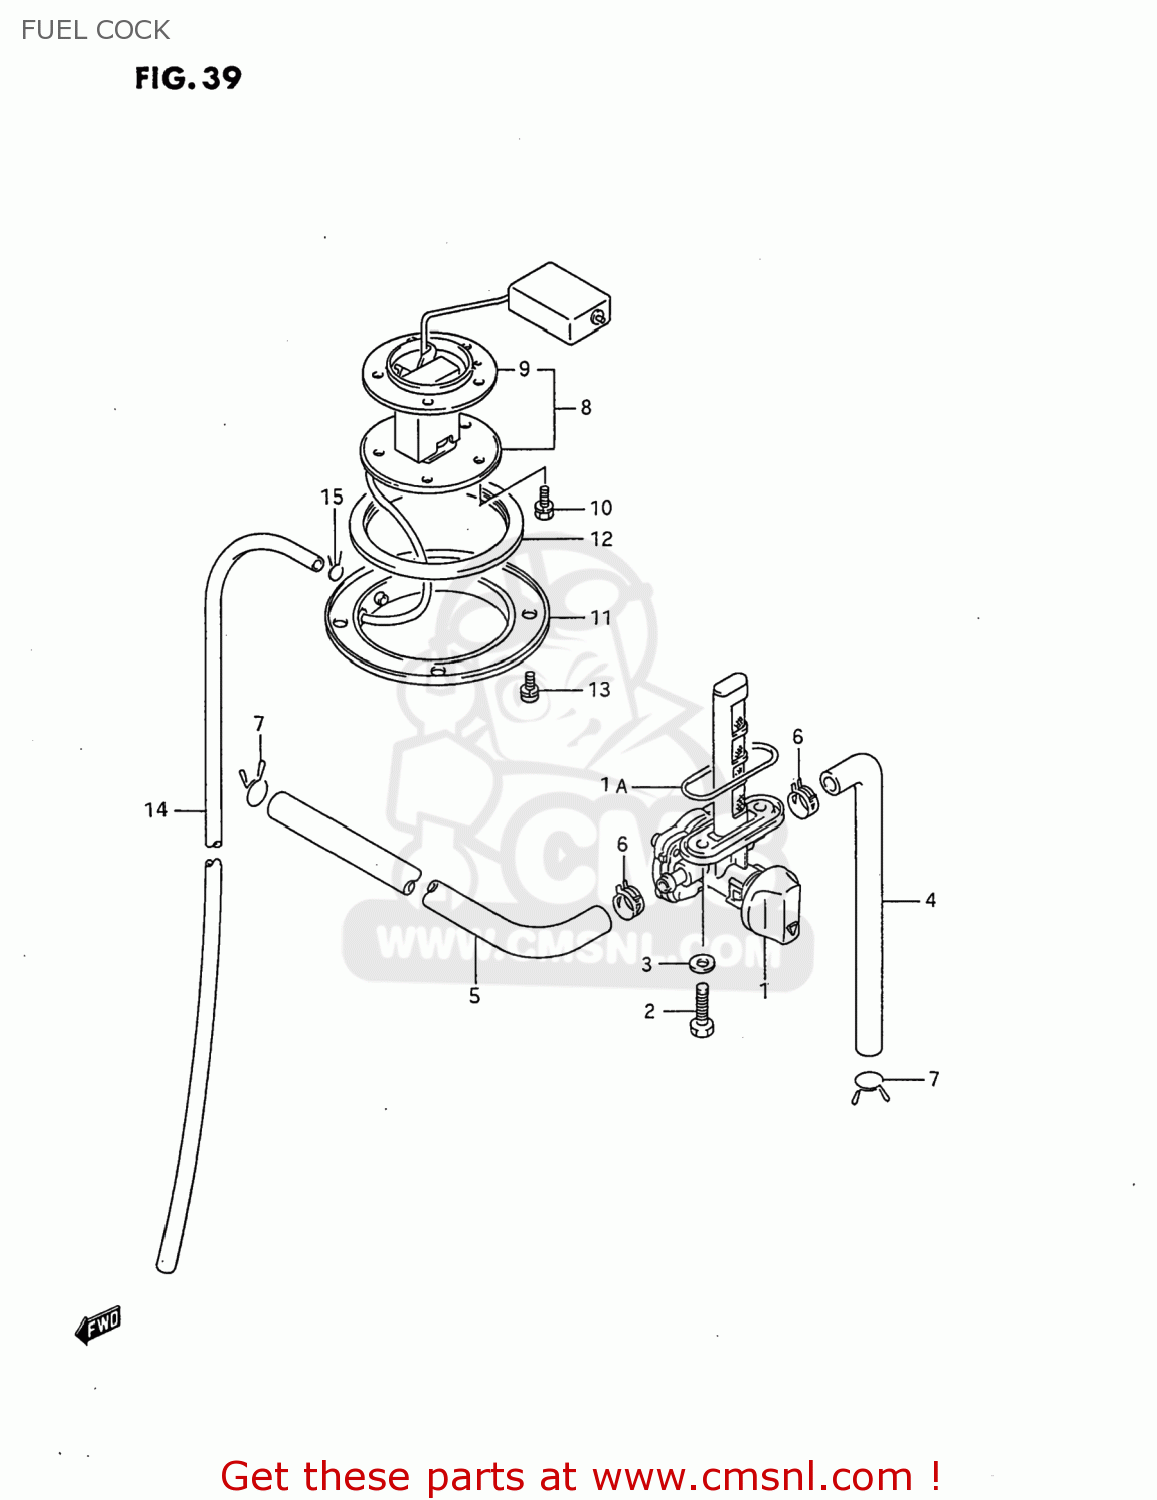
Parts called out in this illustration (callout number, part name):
1	COCK ASSY,FUEL
1A	O RING
2	BOLT(6X20)
3	GASKET(6.4X11.5X0.8) (NAS)
4	HOSE (7X12X150)
5	HOSE (7X12X330)
6	CLIP
7	CLIP
8	GAUGE ASSY,FUEL LEVEL SENDER
9	GASKET,FUEL LEVEL GAUGE (NAS)
10	BOLT 5X10
11	PLATE,FUEL DRAIN
12	GASKET,FUEL DRAIN PLATE (NAS)
13	SCREW(5X8)
14	HOSE(5X8.2X2000)
15	CLIP
